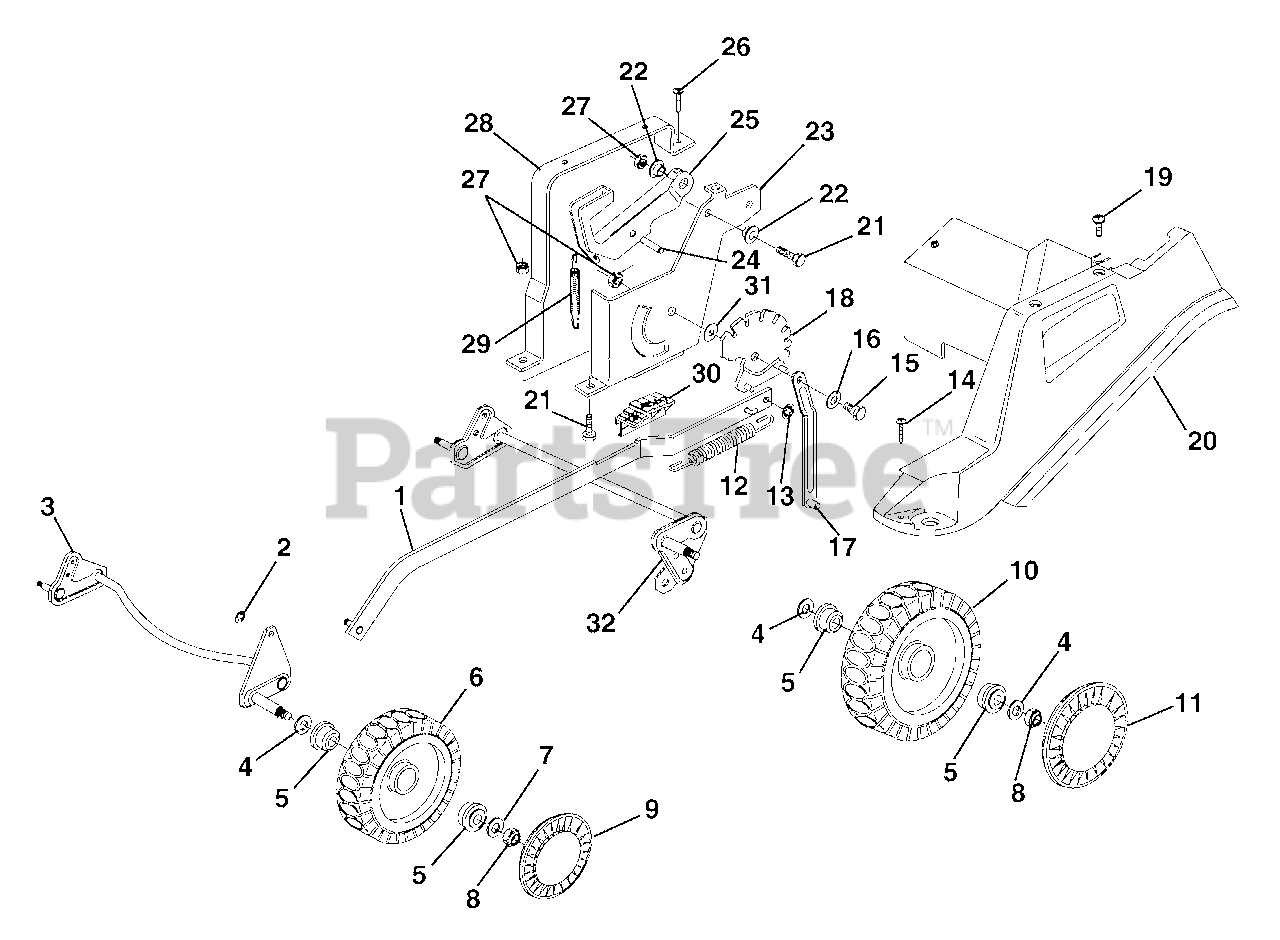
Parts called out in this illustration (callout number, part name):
1	ROD, HEIGHT ADJUSTMENT CONTROL
2	RING, SNAP
3	AXLE, FRONT WHEEL
4	WASHER, ELASTIC M12
5	BEARING
6	WHEEL, FRONT KNOBBLY 170
7	WASHER M8 8.4X16X1.6
9	HUB, CAP FRONT GREY
10	WHEEL, REAR KNOBBLY 210
11	HUB, CAP REAR GREY
13	RING, ELASTIC
14	SCREW 5.5X16
15	PIN, FULCRUM
17	ROD, REAR WHEEL AXLE
18	SECTOR, HEIGHT ADJUSTMENT
19	SCREW 5.5X13
20	DECK, ADJUSTMENT
21	SCREW M8X25
22	BUSHING
23	SUPPORT, HEIGHT ADJUSTMENT
24	PIN 6X28
26	SCREW 5.5X16
27	NUT M8 FLANGE
28	SUPPORT, HANDLE
30	PLATE, CUTTING POSITION
32	NOT USED ON THIS MODEL
